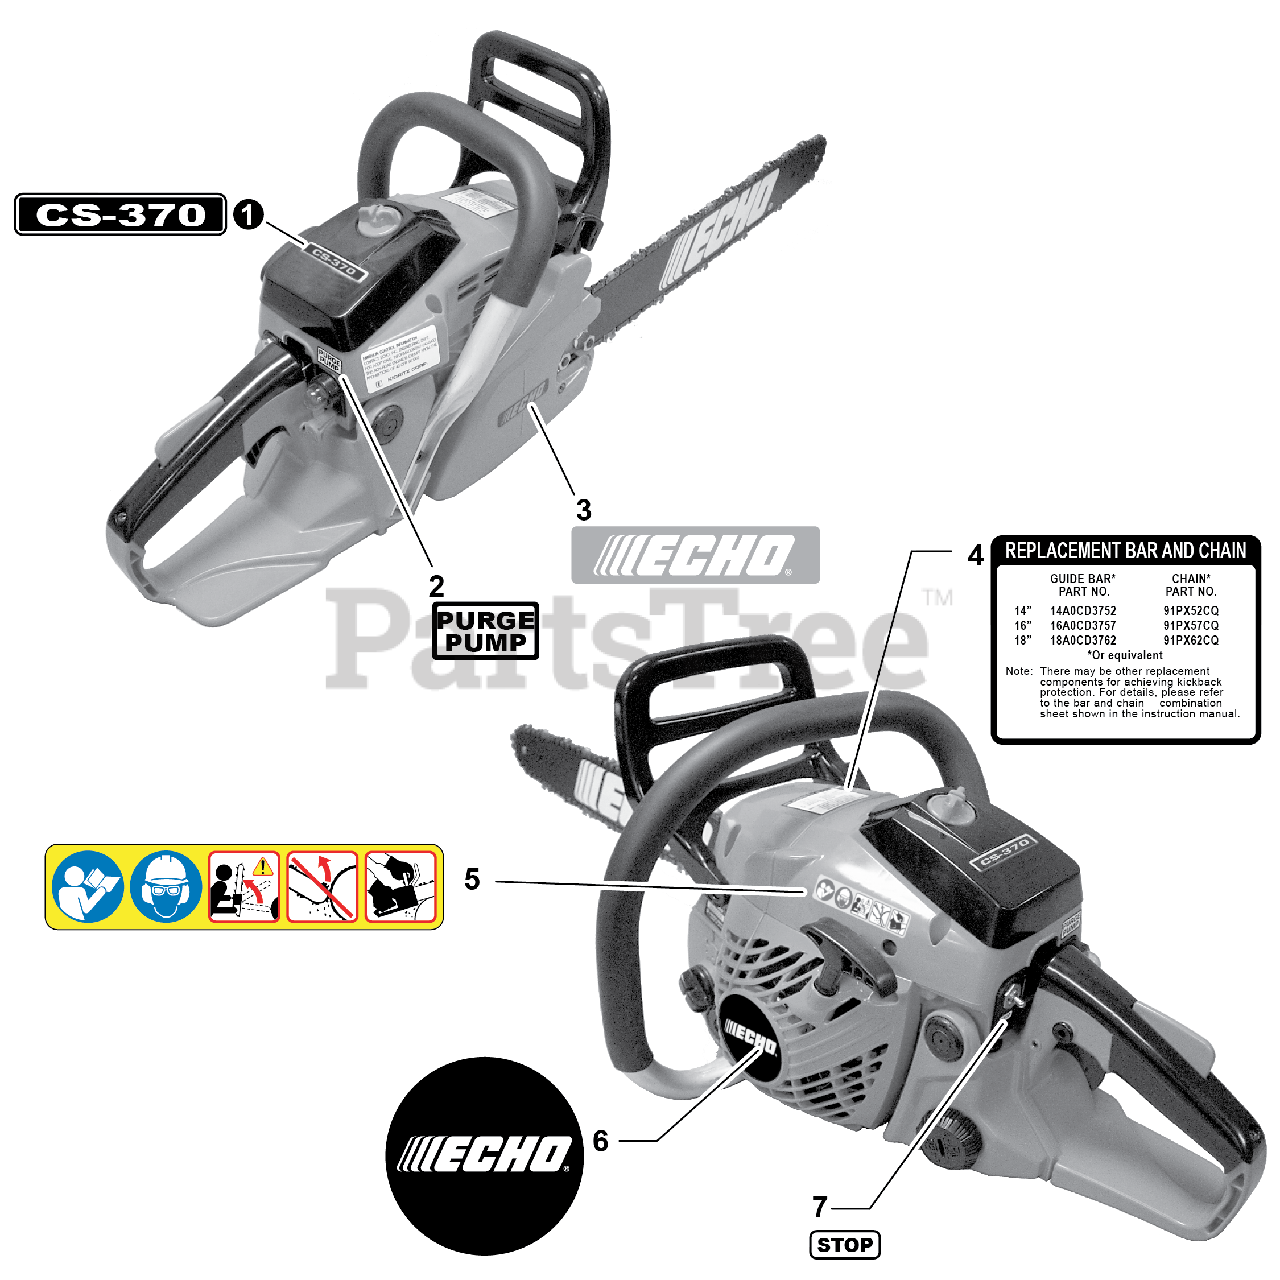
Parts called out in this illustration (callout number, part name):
1	LABEL - MODEL CS-370
2	LABEL, PURGE PUMP
3	LABEL, ECHO
4	LABEL, BAR & CHAIN
5	LABEL, CAUTION
6	LABEL, ECHO
7	LABEL, STOP
